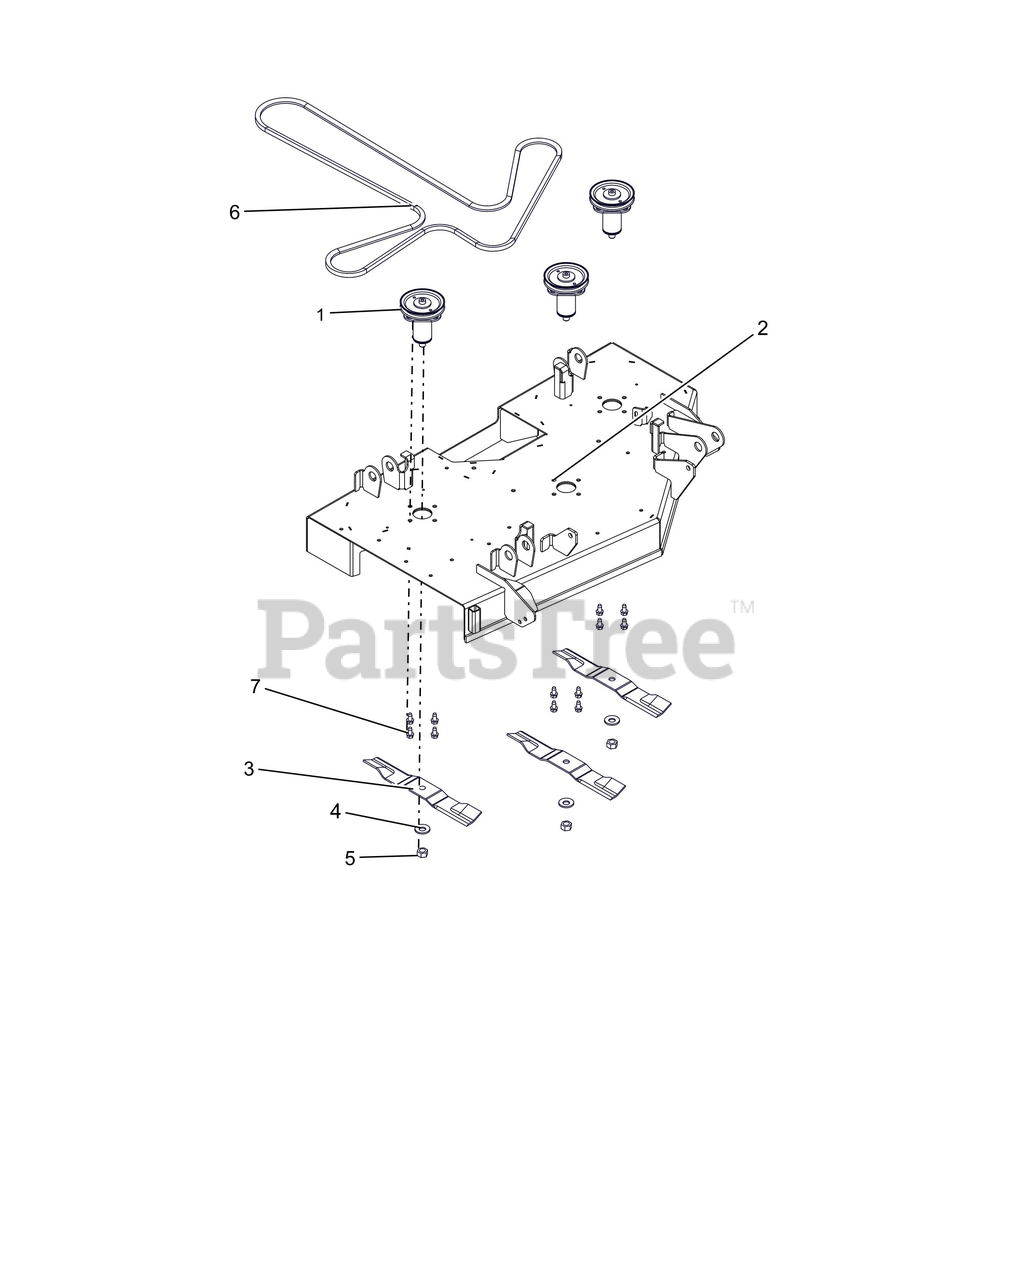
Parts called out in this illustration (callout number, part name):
1	KIT, DECK SPINDLE ASM-IKON-ZTX
2	KIT, 42" ARIENS DECK W/DECALS
3	BLADE, MOWER 15.00"
4	WSHR-BLVL .669X1.535X.138
5	NUT-HEX .62-18 YWZC
6	V-BELT, 4L-WRAPPED
7	@SCR-TAP .38-16X.75 HWH TR YWZ
